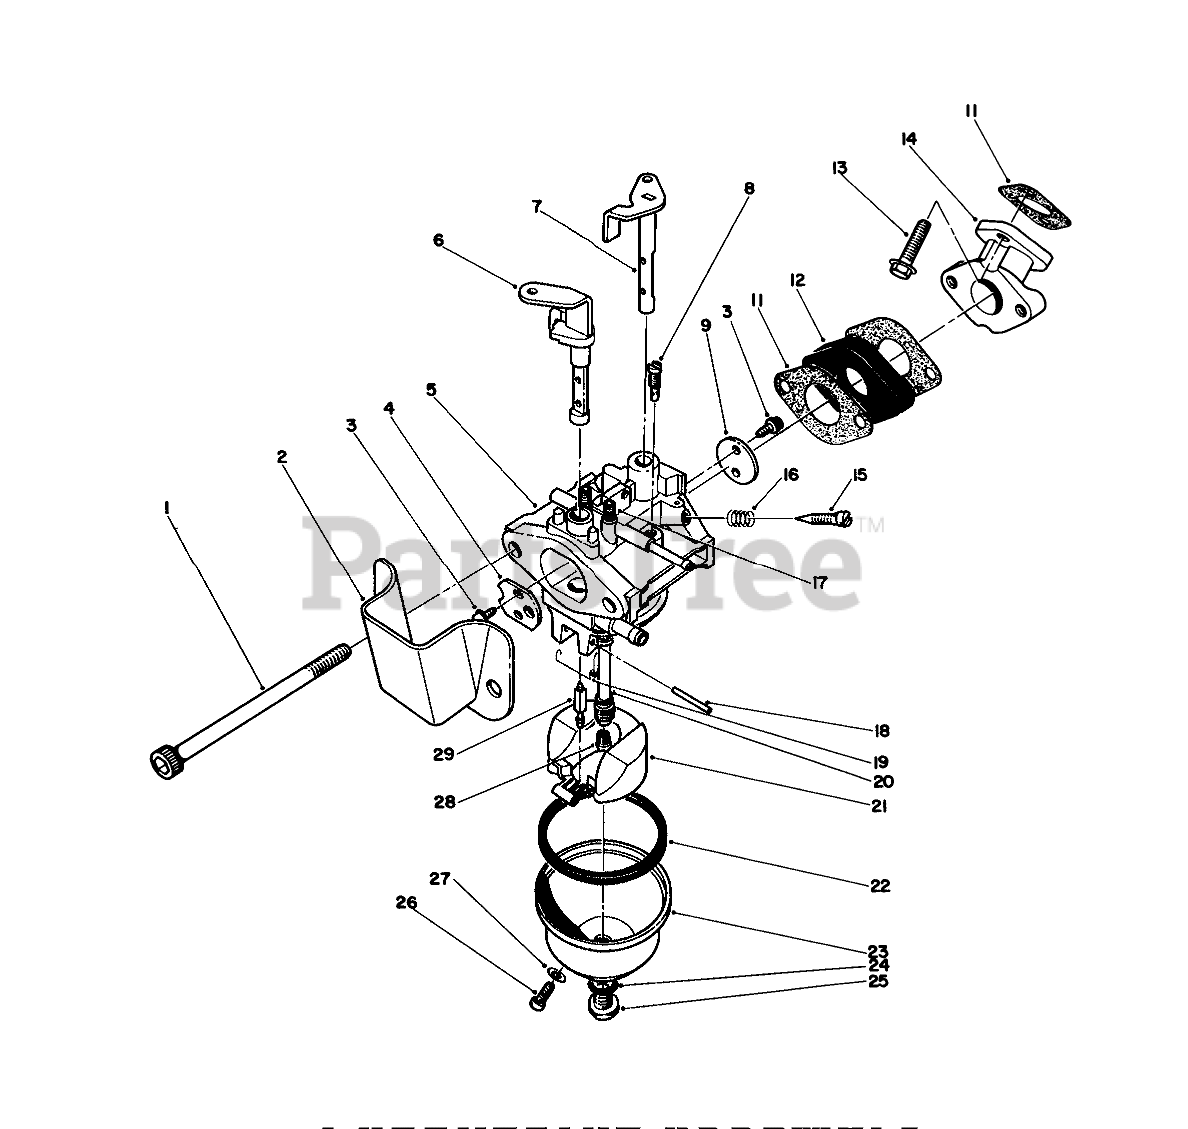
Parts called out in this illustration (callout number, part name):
2	SPIT CUP
3	Screw
4	VALVE
5	Body-Carburetor
6	SHAFT
7	SHAFT
9	VALVE
11	Gasket-Carburetor
12	CARB INSULATOR
14	MANIFOLD
15	ADJUSTER
16	SPRING-PILOT SCREW
17	SPRING
18	PIN-HINGE
19	TORSION SPRING
20	MAIN NOZZLE
21	Float
22	FLOAT BOWL GASKET
24	GASKET
25	SCREW
26	SCREW
27	GASKET
28	MAIN JET
29	NEEDLE
